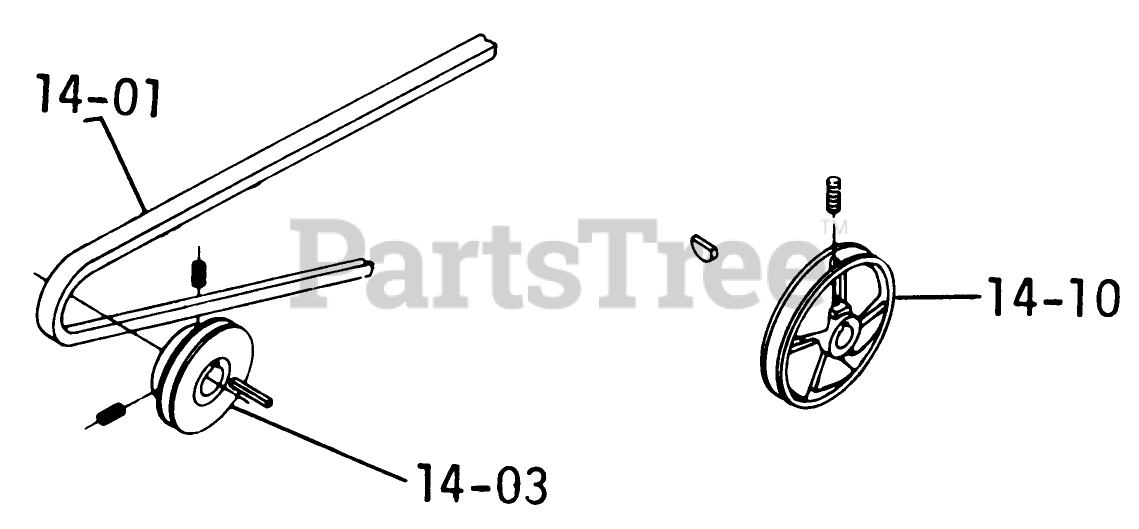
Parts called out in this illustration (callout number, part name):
14-01	V BELT
14-03	PULLEY
14-10	PULLEY
